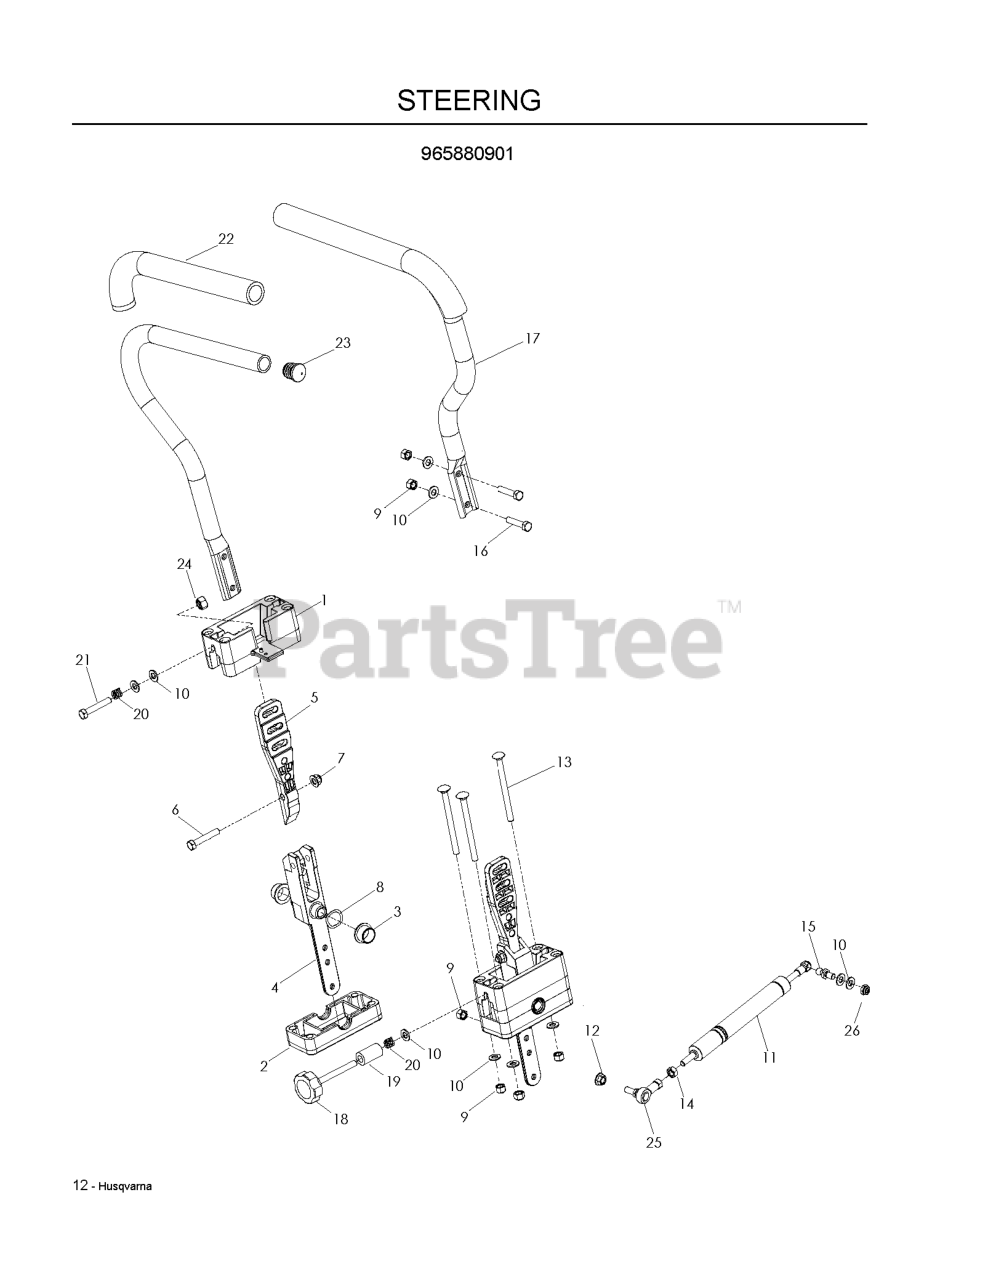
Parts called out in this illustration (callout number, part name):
1	BLOCK, UPPER
2	BLOCK, LOWER
3	BEARING, FLANGE
4	PIVOT.SECTION.DRIVE.CONTROL
5	MOUNT, DR CNTRL HANDLE
6	HCS 5/16C X 1 3/4
7	5/16-18 NYLOC FLANGE NUT
8	WASHER, .825 X 1.087, WAVE
9	NUT 5/16 NYLOC
10	FLAT WASHER 5/16 SAE
11	DAMPENER W/SPRING
12	NUT 5/16C WHIZ
13	RHSNB 5/16-18 X 4 GR 5 ZD
14	NUT M8 X 1.25 STD HEX
15	STUD.BALL.10MM
16	CAPSCREW 5/16 X 1/1/2 HEX HEAD
17	LEVER.DRIVE.W/GRIP
19	DECK LIFT SPACER
21	HCS 5/16-18 X 2 TPBLT GR 5 ZD
22	GRIP, FOAM (GROUND) 15
23	END PLUG 15/16 (BLACK)
24	NUT 5/16C HEX
26	5/16-18 THIN PROF NY
